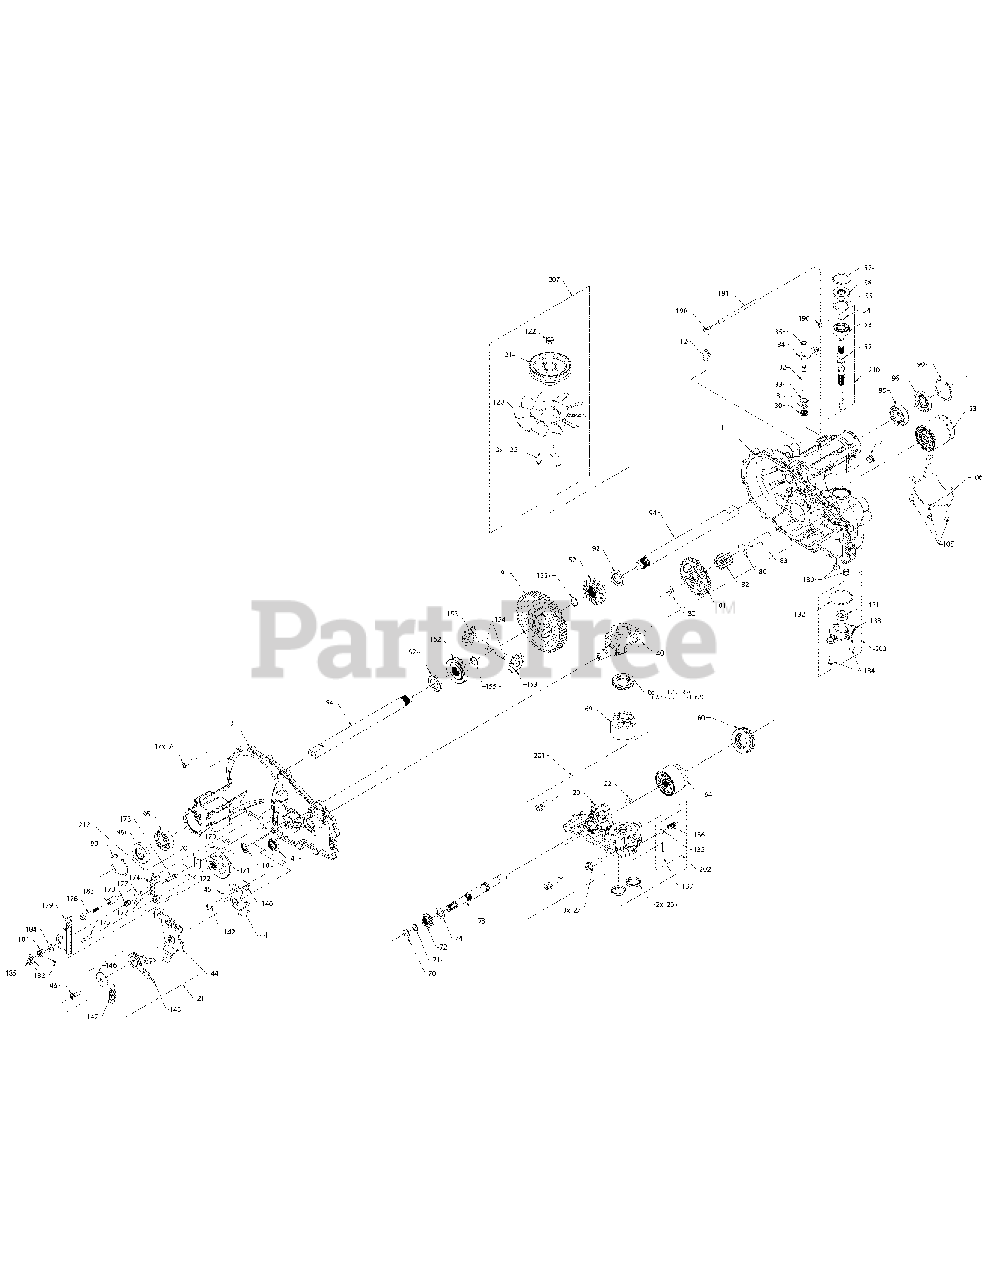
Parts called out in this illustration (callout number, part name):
1	KIT, HOUSING MAIN
2	KIT, HOUSING SIDE
4	PLUG 9/16-18 (METAL)
6	PIN, STANDARD HEADLESS
7	SCREW-HEX FLANGE
10	SEAL, LIP .625 X 1.0
12	ASSEMBLY, FITTING METAL
20	CENTER SECTION, LH CHRG
22	PLATE, BYPASS
23	FILTER, OIL
24	CHECK PLUG
25	CHECK PLUG
26	SEAL, PLUG 1.250 X .250
27	HFHCS 3/8-16 X 1.5 (PATCH)
28	BRG,JRNL
30	SEAL, LIP .375 x .75 x .25
31	RING, RETAINING .375 EXTERNAL
32	ROD, BYPASS
33	RING, RETAINING .750 INTERNAL
34	ARM, BYPASS
35	RING, RETAINING .375 EXTERNAL
40	TRUNNION, SWASHPLATE
41	SEAL, LIP 18 X 32 X 7
44	ARM, CONTROL
45	WASHER, .24 X .88 X .06
46	TWHCS 5.16-24 X 1.00 (PATCH)
52	SHAFT INPUT
53	BRG. BALL 17 X 40 X 12 OPEN 6203
54	RING, RET WIRE .561 ID
55	WASHER, 1.23 X 1.56 X .04
56	SEAL, LIP 17 X 40 X 7
57	RING, RETAINING 1.575 INTERNAL
60	BEARING THRUST
64	ASSEMBLY, CYLINDER BLOCK 16CC
65	BEARING, THRUST BALL 30 X 52 X 13
69	ASSEMBLY, BLOCK 7 PISTON
70	WASHER, .63 X 1.0 X .05
71	RING, RETAINING .625 EXTERNAL
72	GEAR, 14T
73	SHAFT MOTOR
74	WASHER, .72 X 1.16 X .04
80	WASHER, .5 X 1.0 X .03
81	GEAR, 45T
82	GEAR, 11T
83	PIN, JACKSHAFT
90	RING, RETAINING 2.06 INTERNAL
91	GEAR, 60T
92	SPACER, 1.04 X 1.65 X .22
94	SHAFT, AXLE 1.00 X 13.37, DD
95	BEARING, BALL 1.0 X 52 X 15
96	SEAL, LIP 25 X 52 X 10 TC (GRAY)
105	HFHCS 1/4-20 X .75
106	GUARD, FILTER , LH
120	FAN 7.0 (10 BLADE)
121	PULLEY
122	HEX LOCK NUT 1/2-20 (NYLON INSERT)
123	SCREW, HEX 1/2-20 X .875
130	TUBE, CONNECTING
131	GERORTER ASSEMBLY (1.9CC/REV)
132	O-RING 137. .103 X 2.050
133	COVER, CHARGE PUMP
134	SCREW, PAN HEAD 1/4-20 X .75
135	BALL, STEEL 7/16
136	SPRING, RELIEF .42 X .75
136	SPRING RELIEF .42 X .75
137	PIN, SPRING .125 X .875
140	SPACER, .320 X 1.005 X .179
141	ASSEMBLY, RTN, NUETRAL ARM
142	SHCS 5/16-24 X 1 PATCH
145	ASSEMBLY, RTN BIDIRECTIONAL
146	WASHER, .343 X 1.500 X .062
147	SPRING EXTENSION RTN - 44LBS
152	GEAR, BEVEL 14T SPLINE ID
154	PIN, .499 X 1.20
155	RING, SPIRAL RETAINING -.875
163	GEAR, BEVEL 10T
170	PUCK, BRAKE
171	ROTOR, BRAKE
172	PLATE, PUCK
173	BOLT, SQUARE HEAD
174	BRAKE YOKE
175	BOLT, HEX HEAD 1/4-20 X 1 W/PATCH
176	BOLT, HEX HEAD 1/4-20 X 2 W/PATCH
177	PIN,BRK .31 X .73 PLATED
178	SPRING, COMP BRAKE ANTI-DRAG
179	ARM, BRAKE
181	NUT, CASTLE 5/16-24 PL
182	PIN, COTTER 3/32 X 3/4
183	SPACER, .26 X .57 X .87
184	WASHER, .27 X .88 X .12
185	SPRING, BRAKE ARM BIAS
190	CAP, BARBED
191	HOSE, .28 X .15 X 10.00
196	FITTING, BARBED
201	KIT, CENTER SECTION LH CHRG
202	KIT, CHARGE RELIEF
203	KIT, CHARGE
207	KIT, FAN/PULLEY
210	KIT, INPUT SHAFT
211	KIT, RTN BIDIRECTIONAL
212	KIT, BRAKE - YOKE
